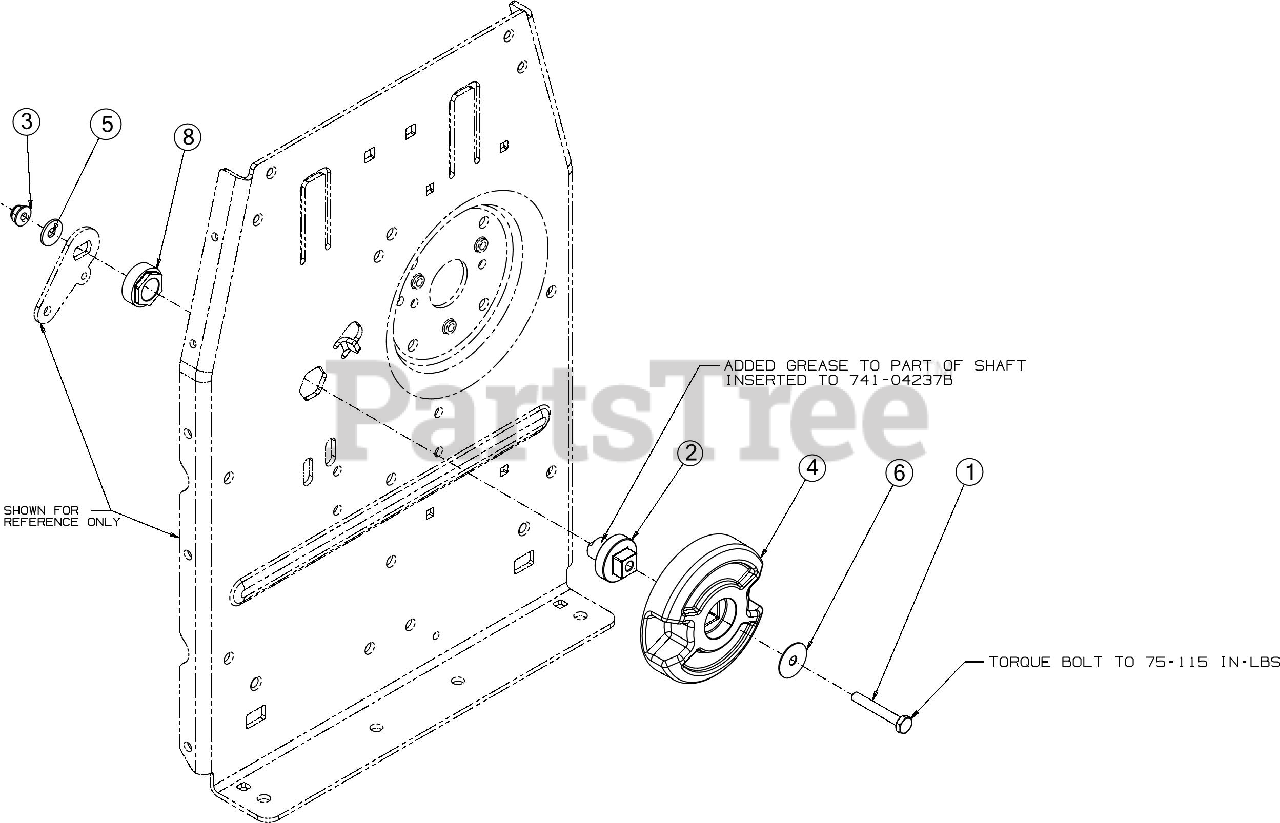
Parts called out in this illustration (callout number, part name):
1	HEX SCREW 1/4-20 x 1.75
2	LINK CLUTCH SHAFT
3	FLANGE LOCK NUT
4	IDLER LUG CLUTCH
5	SPRING WASHER BELL
6	FLAT WASHER
7	GREASE (NOT SERVICEABLE)
8	HEX FLANGE BEARING
